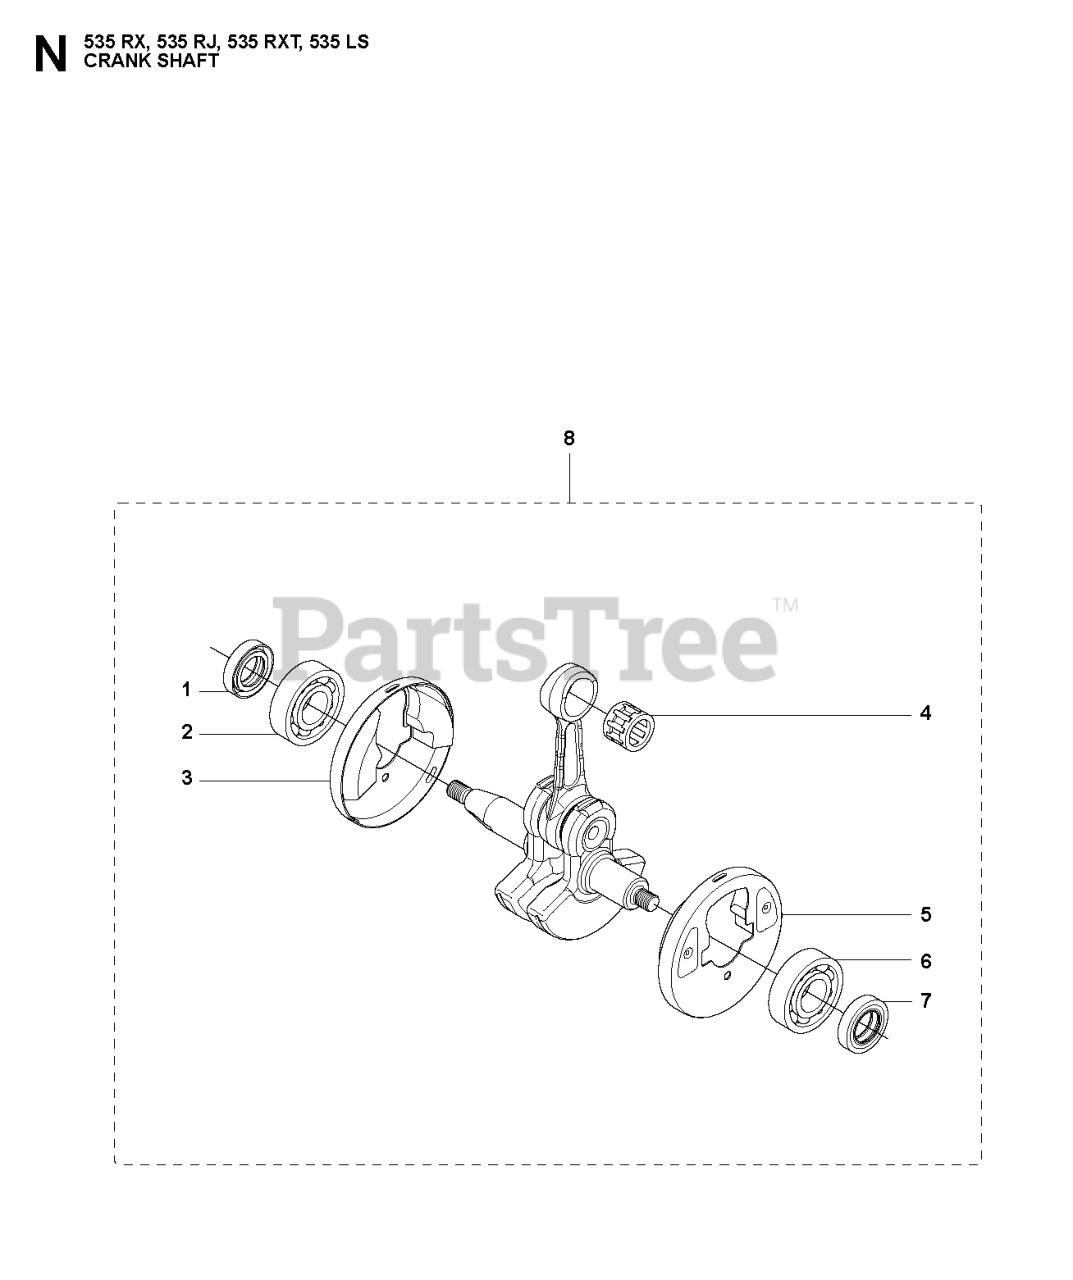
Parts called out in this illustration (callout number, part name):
1	SEALING RING
2	BALL BEARING
4	SUPPORT BUSHING
6	BALL BEARING
7	SEALING RING
8	CRANKSHAFT
